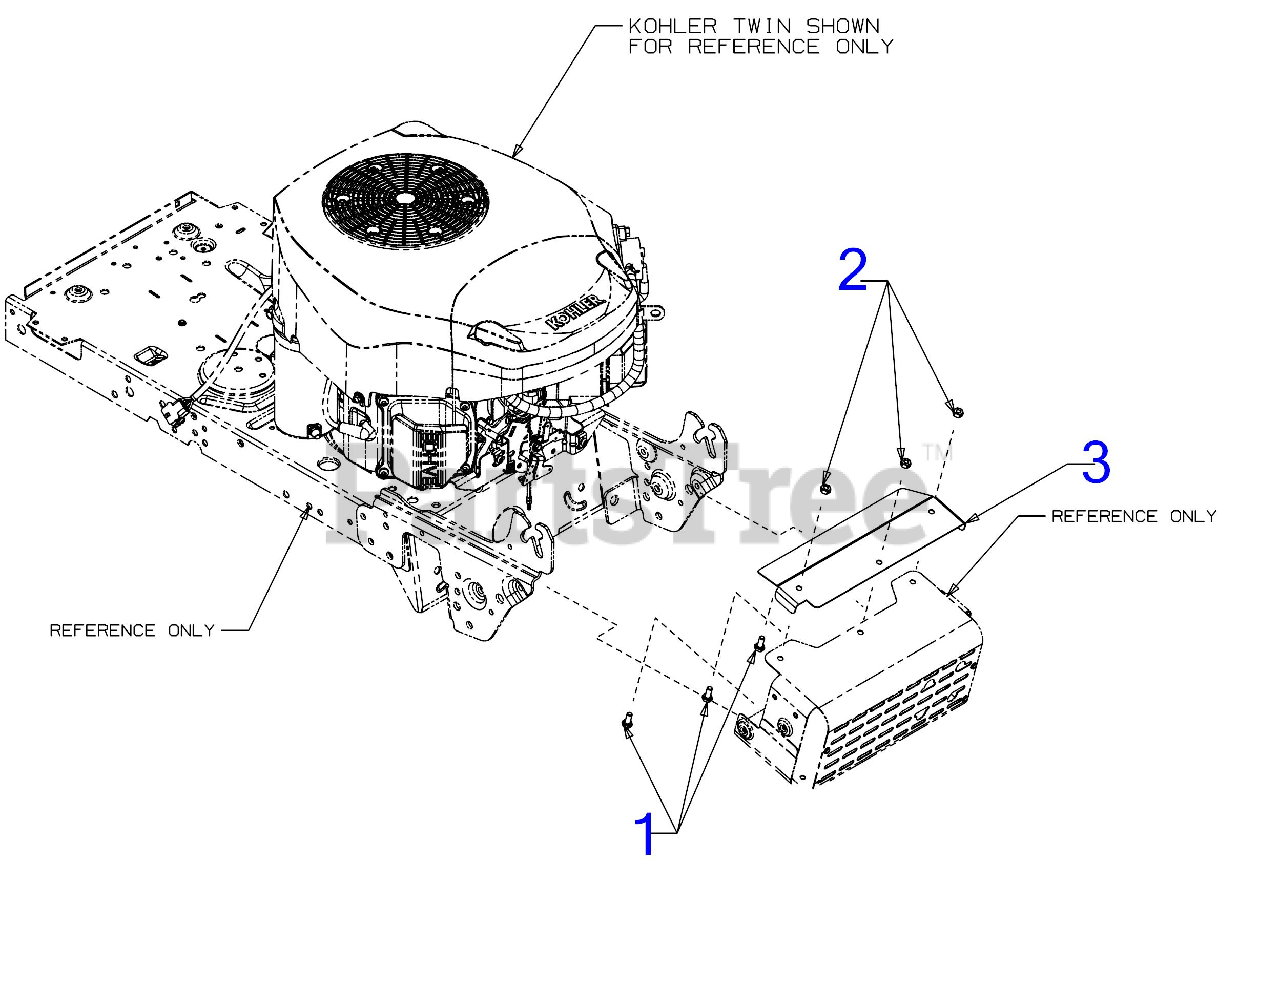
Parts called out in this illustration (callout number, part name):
1	SCREW 1/4-20 x .620 GR5
2	HEX NUT
3	MUFFLER SHIELD EXTENSION
